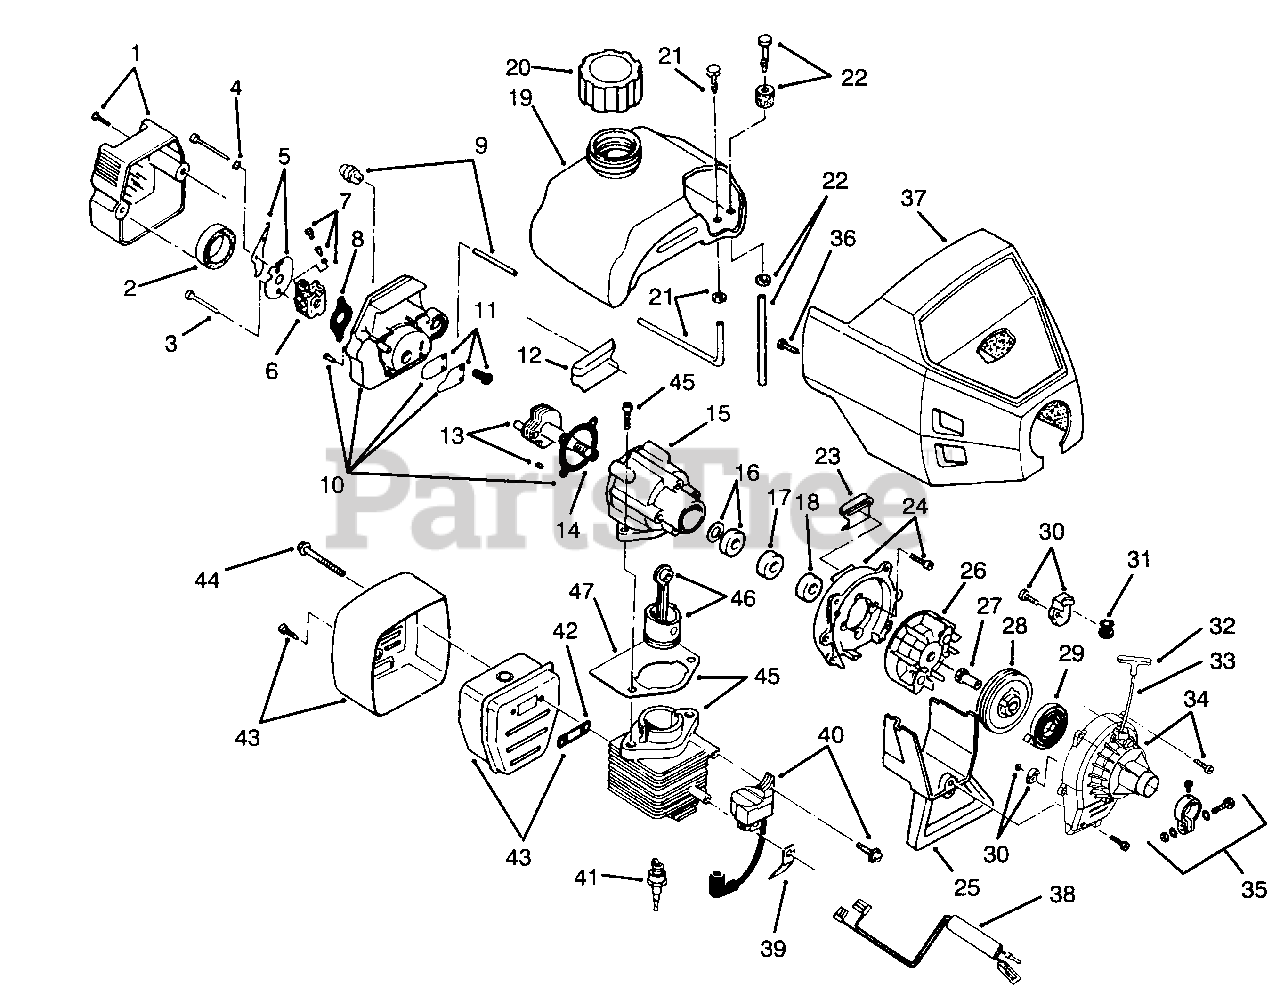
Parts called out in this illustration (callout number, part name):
1	Assy.-Carburetor/Air Clean. (Inc. Ref. No.2)
2	Filter-Air Cleaner
3	Screw-Carburetor
4	Washer-Wave
5	Choke-Lever and Plate
6	Assembly-Carburetor
7	Throttle Adj.-Walbro
8	Gasket-Carb. (10 Pack)
9	Assy.-Primer and Hose
10	Assembly-Carb. Mount (Incl. Ref. 11 & 12)
11	Assembly-Reed
12	Pad-Mounting, Rear
13	Assembly-Power Shaft
14	Gasket (10 Pack)
15	Assy.-Crankcase (Incl. Ref. No.14-18)
16	Assembly-Inner Bearing
18	Assembly-Outer Bearing
19	Assembly-Fuel Tank (Incl. Ref. No.20-22)
20	Assembly-Fuel Cap
21	Assembly-Return Line
22	Assembly-Fuel Line
23	Pad-Mounting, Front
24	Assembly-Shroud
25	Shroud Extension & Stand
26	Assembly-Flywheel
27	Square Nut Drive
28	Assembly-Recoil Pulley
29	Spring-Recoil
30	Assembly-Pulley Retainer
31	Guide-Rope
32	Handle-Pull
34	Assembly-Starter Housing
35	Assembly-Upper Clamp
36	Engine Cover Screws
37	Assembly-Engine Cover
38	Assembly-Lead Wire
39	Ground Tab
40	Assembly-Module
41	Spark Plug
42	Gasket-Exhaust (10 Pack)
43	Assembly-Muffler
44	Bolt-Muffler Mounting
45	Assembly-Cylinder
46	Assy.-Piston and Rod
